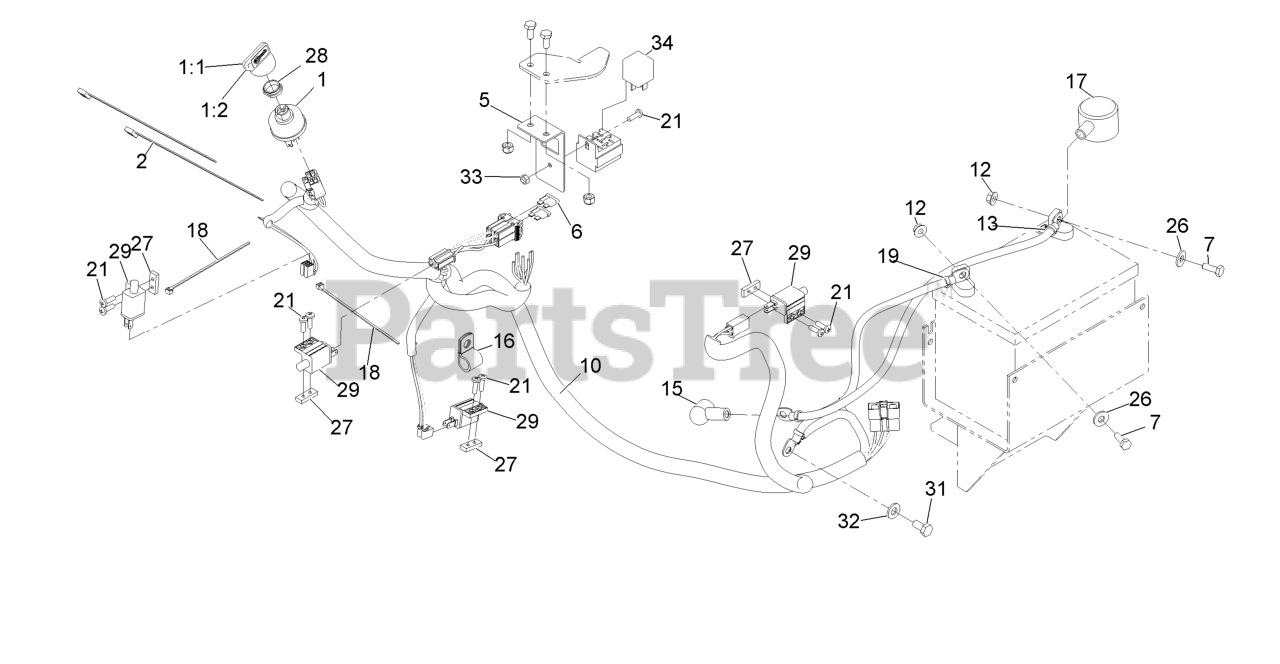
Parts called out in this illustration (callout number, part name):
1:1	KEYS-IGNITION (SPARE PAIR
1:2	KEY-IGNITION
2	TIE-PLASTIC
5	BRACKET-FUSE AND RELAY
6	FUSE-BLADE TYPE, 20 AMP
7	SCREW-HH
13	ASM,POSITIVE BATTERY CABL
15	INSULATOR-SOLENOID
16	CLIP-LOOM
17	INSULATOR-BATTERY
18	TIE-CABLE
19	CABLE-BATTERY, NEGATIVE
21	SCREW-PPH
26	WASHER-FLAT
27	PLATE-TAPPED
28	NUT-SWITCH, IGNITION
29	SWITCH-OPEN, NORMALLY
31	SCREW-HH
32	WASHER-PLAIN
33	NUT-LOCK, NI
